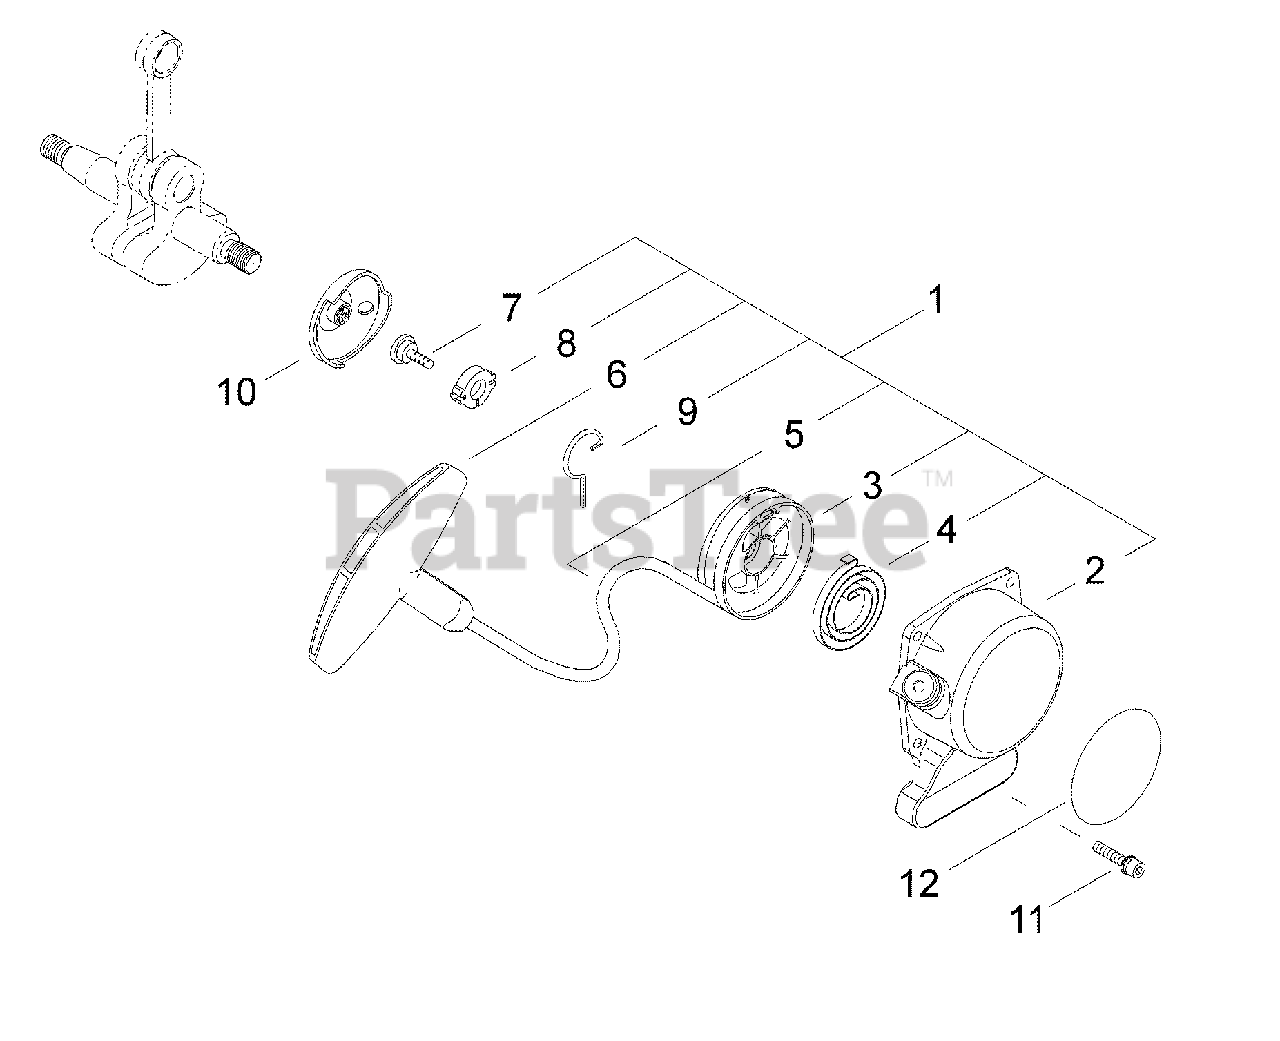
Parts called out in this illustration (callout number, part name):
1	STARTER ASSY
2	CASE, STARTER
3	REEL, ROPE
4	SPRING, REWIND
5	ROPE, STARTER
6	GRIP, STARTER
7	SCREW - 5
8	WASHER - 5
9	PAWL, STARTER
10	STARTER PAWL ASSY
11	SCREW - 4X14
12	LABEL - C4
